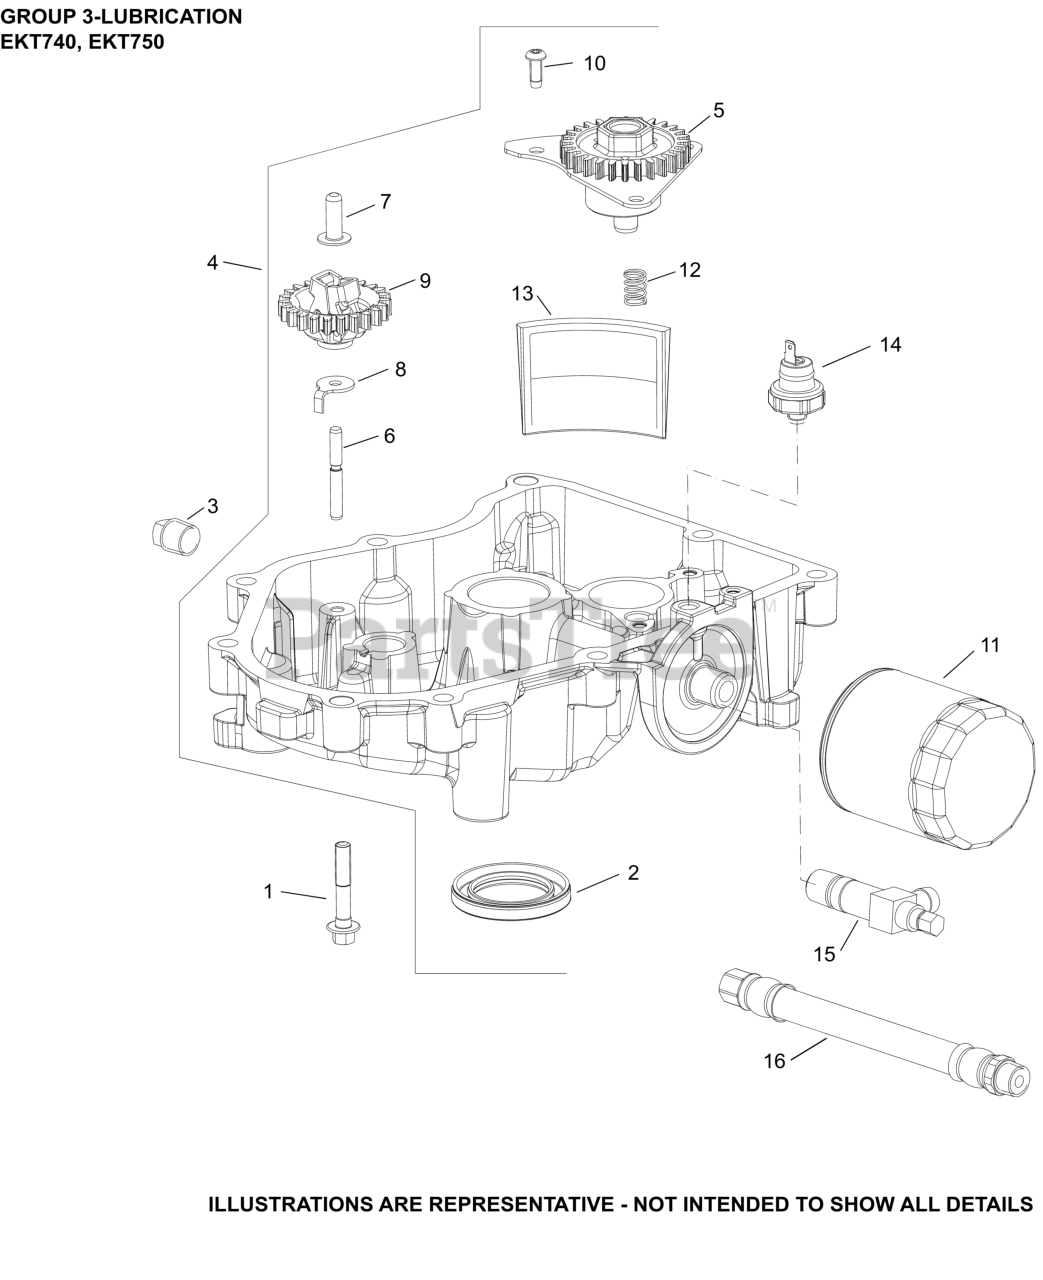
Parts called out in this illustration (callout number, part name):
1	SCREW, FLG M8X1.25X45
3	PLUG, SQ HD PIPE 3/8"
7	PIN, GOVERNOR REGULATING
8	TAB, LOCKING
9	KIT, GOVERNOR GEAR
11	OIL FILTER
13	SCREEN, OIL
NI	SPRING, COMPRESSION
NI	SCREW, BUTTON HEAD
NI	SWITCH, OIL PRESSURE(NC 3-6 PSI TO OPEN)
NI	SHAFT, GOVERNOR GEAR
NI	PRESSURE RELIEF BALL
